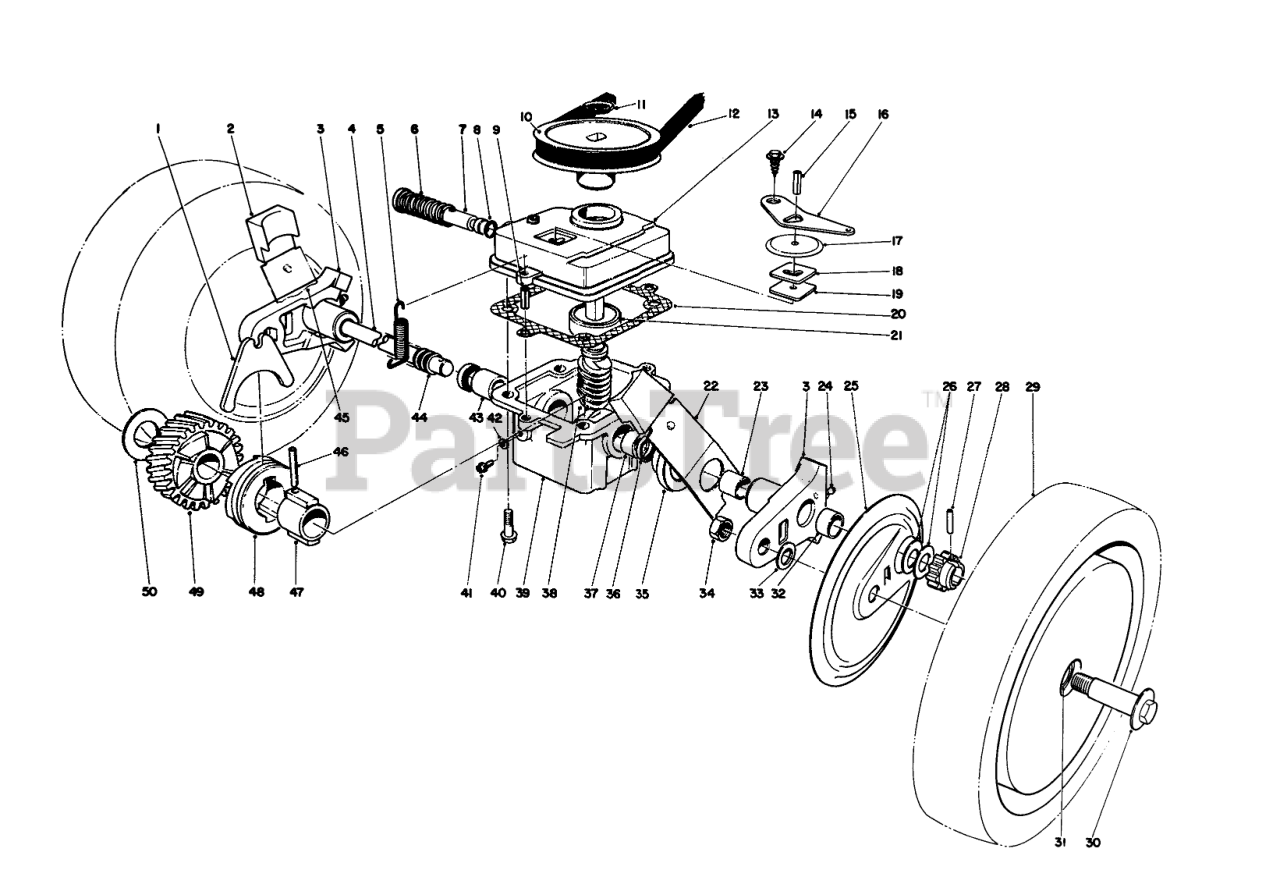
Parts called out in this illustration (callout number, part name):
1	SHIFTER FORK
2	KNOB-ARM
3	Pivot Arm (Incl. Ref. #23, 24&32)
4	DRIVE SHAFT (SERVCE)
5	TENSION SPRING
6	SPRING
7	SHIFTER ROD
8	O-RING
9	3/16 X 1/2 ROLL PIN
10	PULLEY
11	PUSH-ON 93-3236
12	V BELT
13	GEAR CASE COVER
14	Screw
15	SPIROL PIN H D
16	SHIFTER ARM
17	DUST COVER
18	LATCH PLATE
19	DUST FILTER
20	GASKET
21	BEARING
22	SPRING ARM ASM SP LH
23	BUSHING
24	FITTING-GREASE
25	WHEEL COVER
26	THRUST WASHER
27	Pin
28	PINION GEAR 14T
29	Wheel, Tire & Gear Assembly (Incl. Ref. #31)
30	WHEEL BOLT
31	BUSHING
32	BUSHING
33	WASHER
34	NUT-LOCK
35	CAP-END
36	SEAL-OIL
37	BUSHING
38	Worm Shaft & Gear (incl. Ref. #49)
39	Gear Case (Incl. Ref. #36-37 & 43)
40	Screw
41	NYLON SCREW
42	FILL PLUG GASKET
43	BUSHING
44	COVER-SHAFT, DRIVE
45	SPRING ARM ASM SP RH
46	COIL PIN
47	SLEEVE
48	CLUTCH JAW
49	Helical Gear
50	THRUST WASHER
